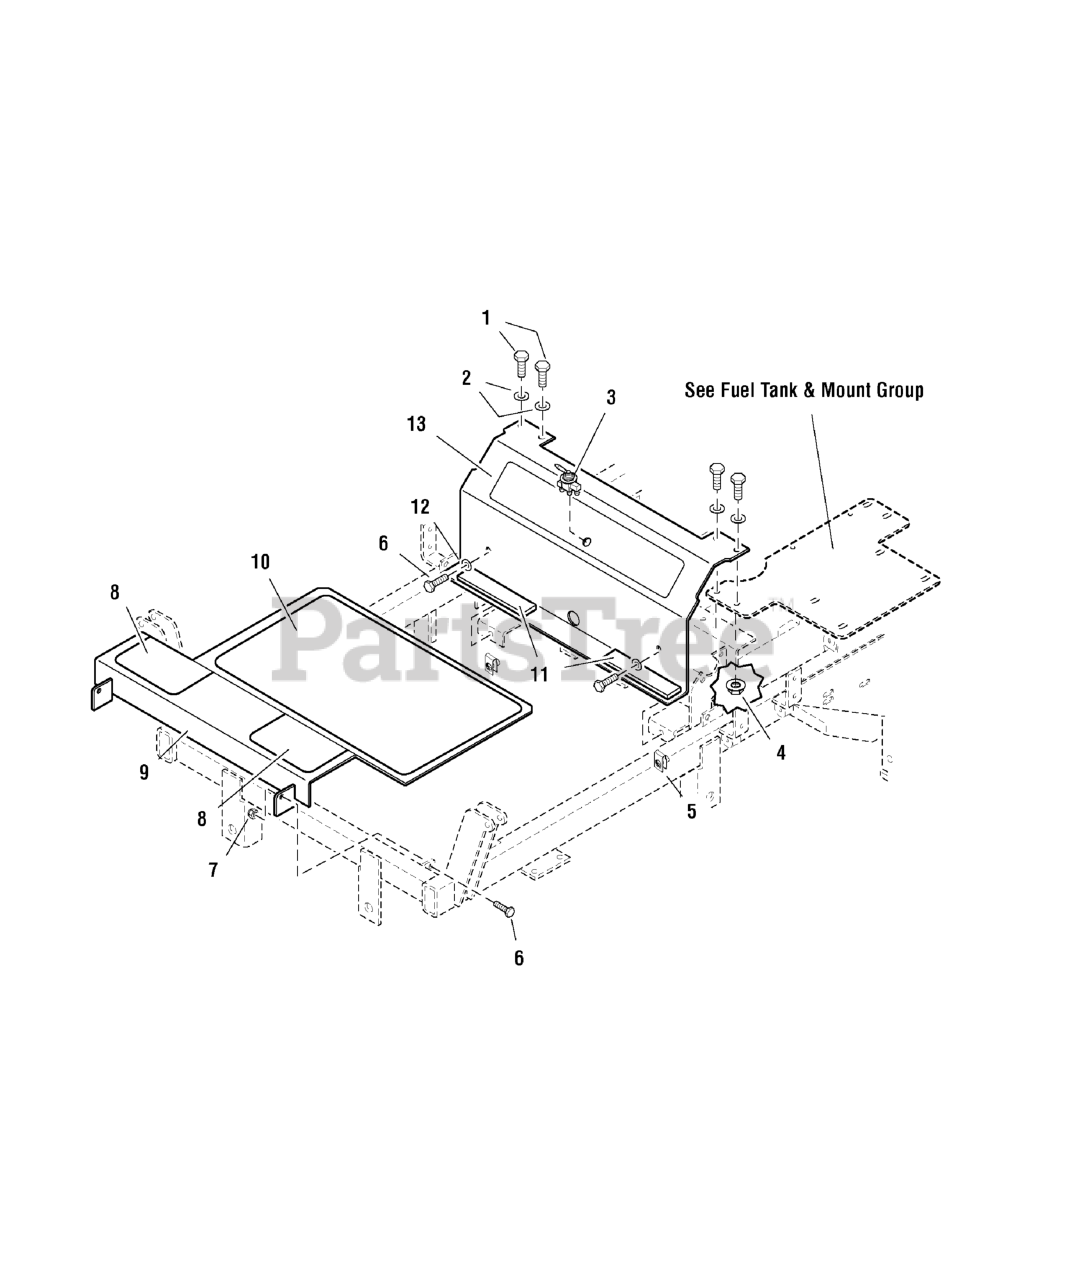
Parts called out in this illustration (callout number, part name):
1	BOLT, 3/8-16 X 1" GD5 CZ
2	WASHER, 3/8 SAE
3	VALVE, Fuel Shut Off, 4-Way
4	NUT, 3/8-16 Hex Serrated Flange
5	BODY CLIP, 5/16-18-7GA MATERIAL
6	BOLT, 5/16-18 X 3/4 GD5
7	NUT, 5/16-18 Hex Nylon Lock
8	SAFETY WALK
9	FLOOR PAN
10	SAFETY WALK, 11.50 X 19.00
11	RUBBER PAD
12	WASHER, 5/16" SAE
13	BRAKE COVER PANEL ASSEMBLY
